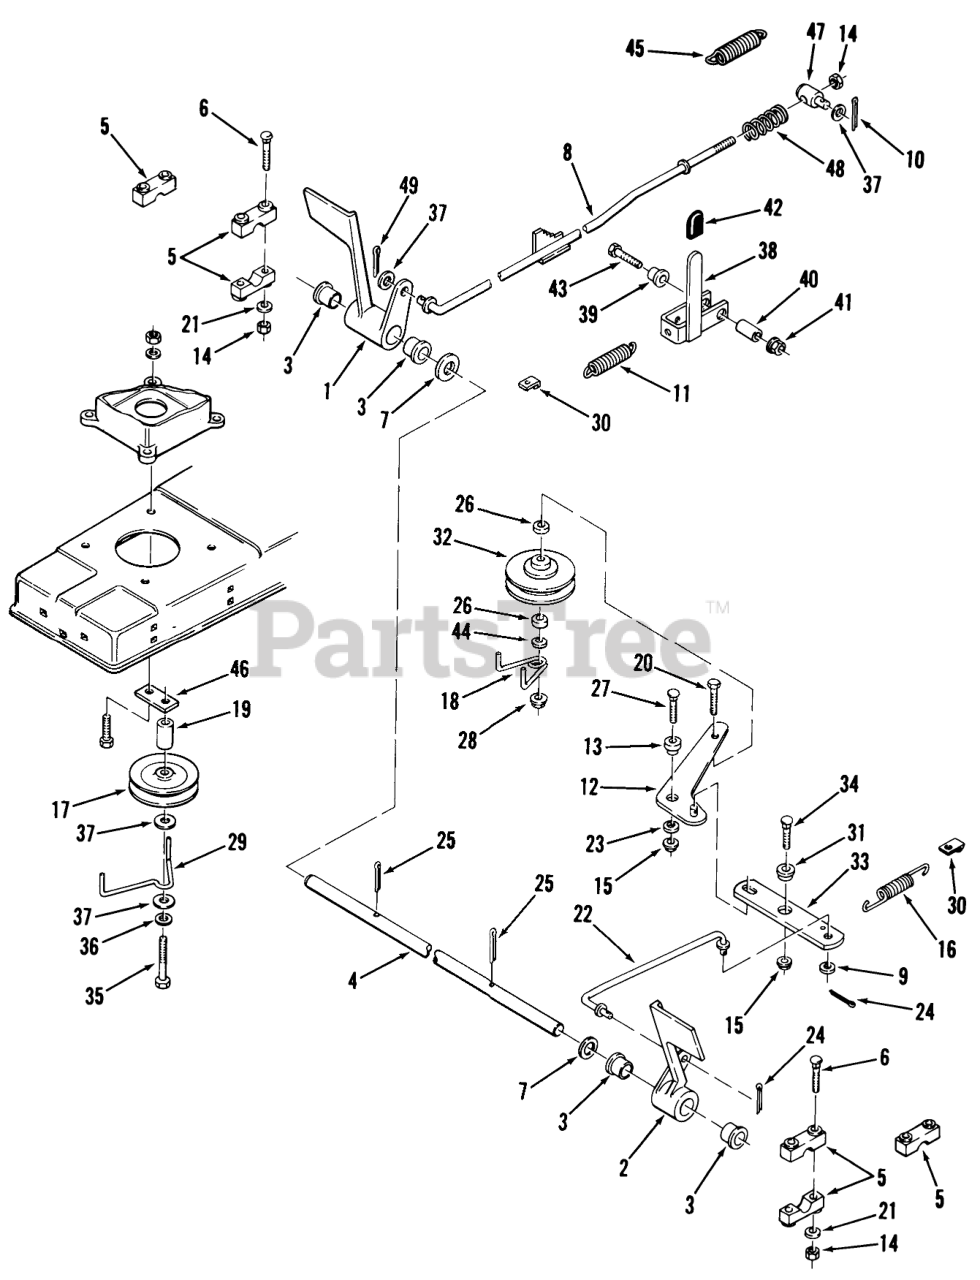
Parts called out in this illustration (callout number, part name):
1	Pedal-Brake (Includes Item 3)
2	Pedal-Clutch (Includes Item 3)
3	BEARING
4	SHAFT-PEDAL
5	BLOCK PIVOT
6	Washer
7	Washer
8	Brake Rod
9	WASHER 5/16 SAE
10	Pop Rivet
11	SPRING-EXTENSION
12	IDLER ARM ASSY R
13	SPACER-IDLER ARM
14	Nut
15	LOCKNUT-FLANGE
16	SPRING
17	PULLEY-IDLER STATION
18	BELT GUIDE
19	SPACER
20	Bolt
21	WASHER 5/16 SAE
22	ROD-CLUTCH R
23	Washer
24	Pop Rivet
26	SPACER
27	Carriage Bolt
28	LOCKNUT-FLANGE
29	RETAINER-BELT
30	CLIP - SPRING
31	SPACER
32	IDLER PULLEY
33	BAR-CLUTCH
34	Bolt
35	Bolt
36	LOCKWASHER
37	Washer
38	PAWL-HANDLE ASSY
39	SPACER
40	SPACER
41	LOCKNUT-FLANGE
42	GRIP
43	Bolt
44	Washer
45	SPRING-EXTENSION
46	BLOCK-SPACER
47	TRUNNION-LIFT
48	SPRING FRICTION
49	Cotter Pin
